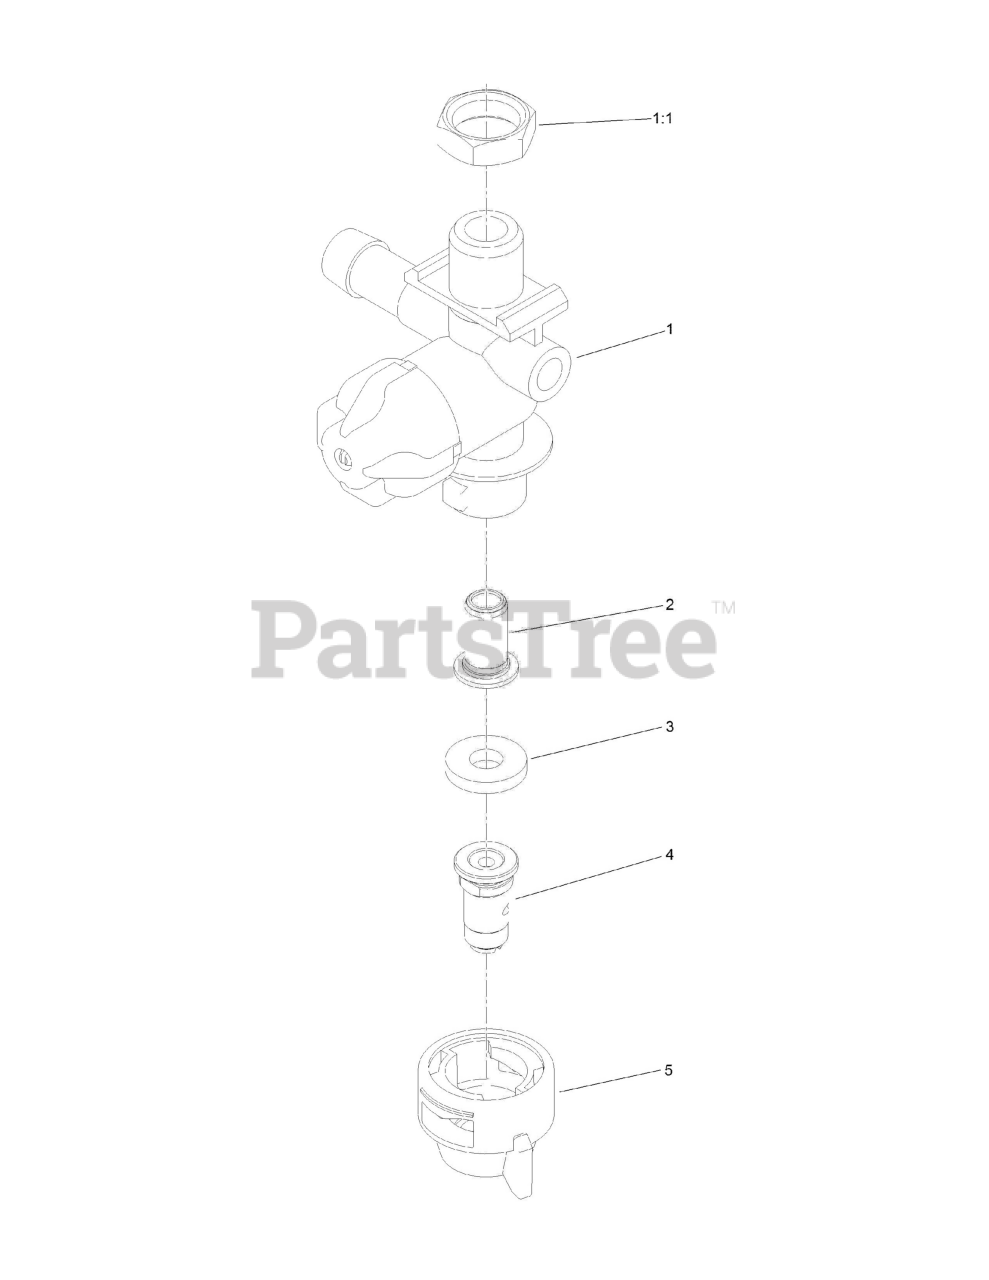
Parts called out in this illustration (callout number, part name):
1	RH NOZZLE BODY ASM
1:1	NUT-NYLON
2	STRAINER-TIP
4	NOZZLE-SPRAY, WHITE
5	CAP-NOZZLE
